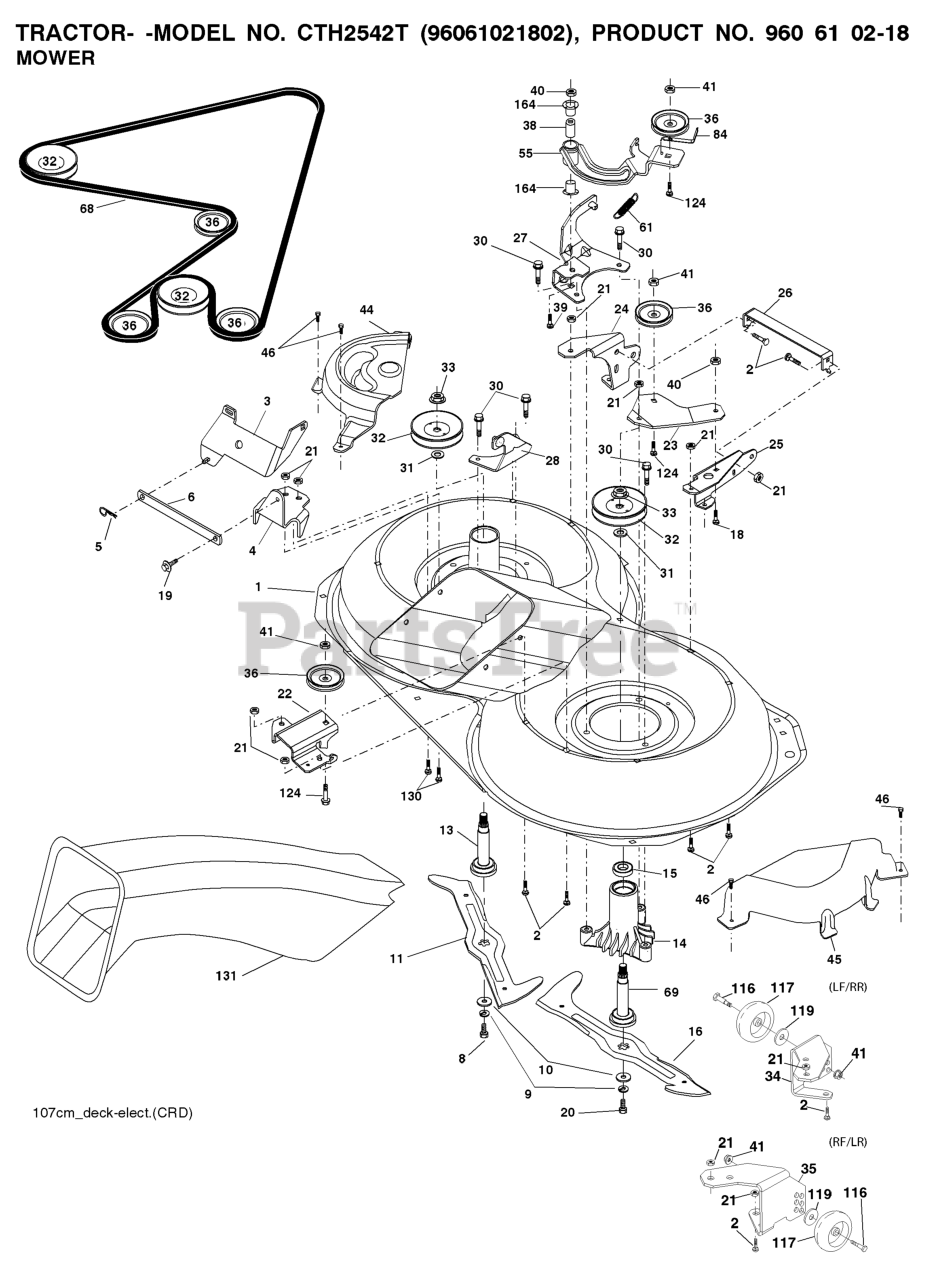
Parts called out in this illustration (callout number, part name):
1	Housing Asm. Mower 107 CRD
2	RP BOLT 5/16-18 X3/4 ZN/YEL GR
5	RETAINER-SPRNG RB
6	BAR.SWAY.92.CRD
8	BOLT.3/8-24X1.25 GR8
9	LOCKWASHER
10	WASHER.BLADE
11	BLADE.3N1.LH.CRD
13	SHAFT ASM VENT
14	HOUSING.MANDREL.VENTED (MACHD)
16	BLADE.3N1.RH.CRD
19	BOLT SHD 5/16-18
20	BOLT.3/8-24X1.25GR8. LHTHRD
21	LOCKNUT
22	BRACKET.IDLER.RR.107.CRD
24	BRACKET
25	BRACKET RF
26	SUPPORT
28	BRACKET
30	SCREW, WASHER HEAD
31	WASHER.SPACER.MANDREL
32	PULLEY.MANDREL.4.80 PD.2006
33	NUT.FLANGE.LOCK.TOP
34	BRACKET
35	BRACKET
36	PULLEY.IDLER.4.25
41	NUT LOCK FLG 3/8-16 UNC
45	COVER.MANDREL.RH.CRD
46	SCREW.1/4-20X5/8
55	ARM.IDLER.107.CRD
61	SPRING
68	HEX-BELT 107 MOWER
69	SHAFT.ASM.W/LWR.BRG.RH.THREAD
84	KEEPER, BELT IDLER
116	BOLT.SHOULDER.3/8-16X3-5/8.
117	RP WHEEL. GUAGE RALLY
119	WASHER
124	BOLT.3/8-16X1.50
130	BOLT.CARR.SQNK.5/16-18UNC.X3/4
131	CHUTE BAGGER
164	BRNG T
